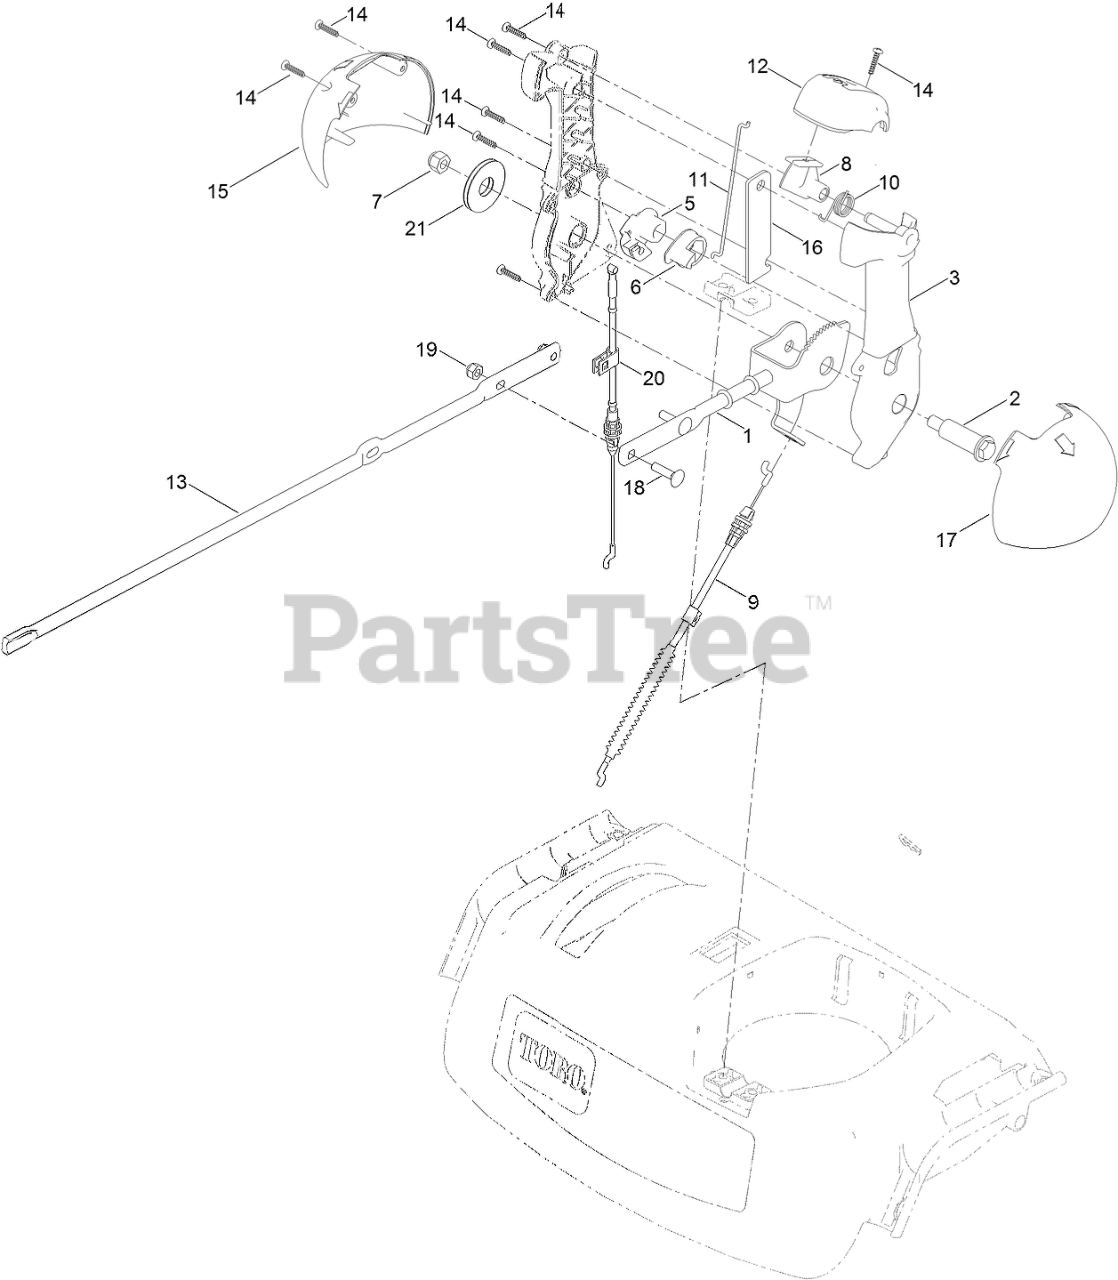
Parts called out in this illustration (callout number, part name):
1	ROD-CONTROL, CHUTE
2	SCREW-SHOULDER, HWH
3	CHUTE CONTROL LEVER ASM
5	LEVER-CABLE, DEFLECTOR
6	PAWL-LATCH
7	NUT-HEX
8	TRIGGER-LATCH
9	CABLE-CONTROL, DEFLECTOR
10	SPRING-TORSION
11	LINK-LATCH
12	CAP-LEVER
13	ROD-CHUTE, ROTATION
14	SCREW-PPH
15	GLOBE-QUICKSTICK, RH
16	PLATE-STIFFNER
17	GLOBE-QUICKSTICK, LH
18	BOLT-CARR
19	NUT-HEX
20	CABLE-RELEASE, CHUTE
21	WASHER-FRICTION, COMPOSITE
